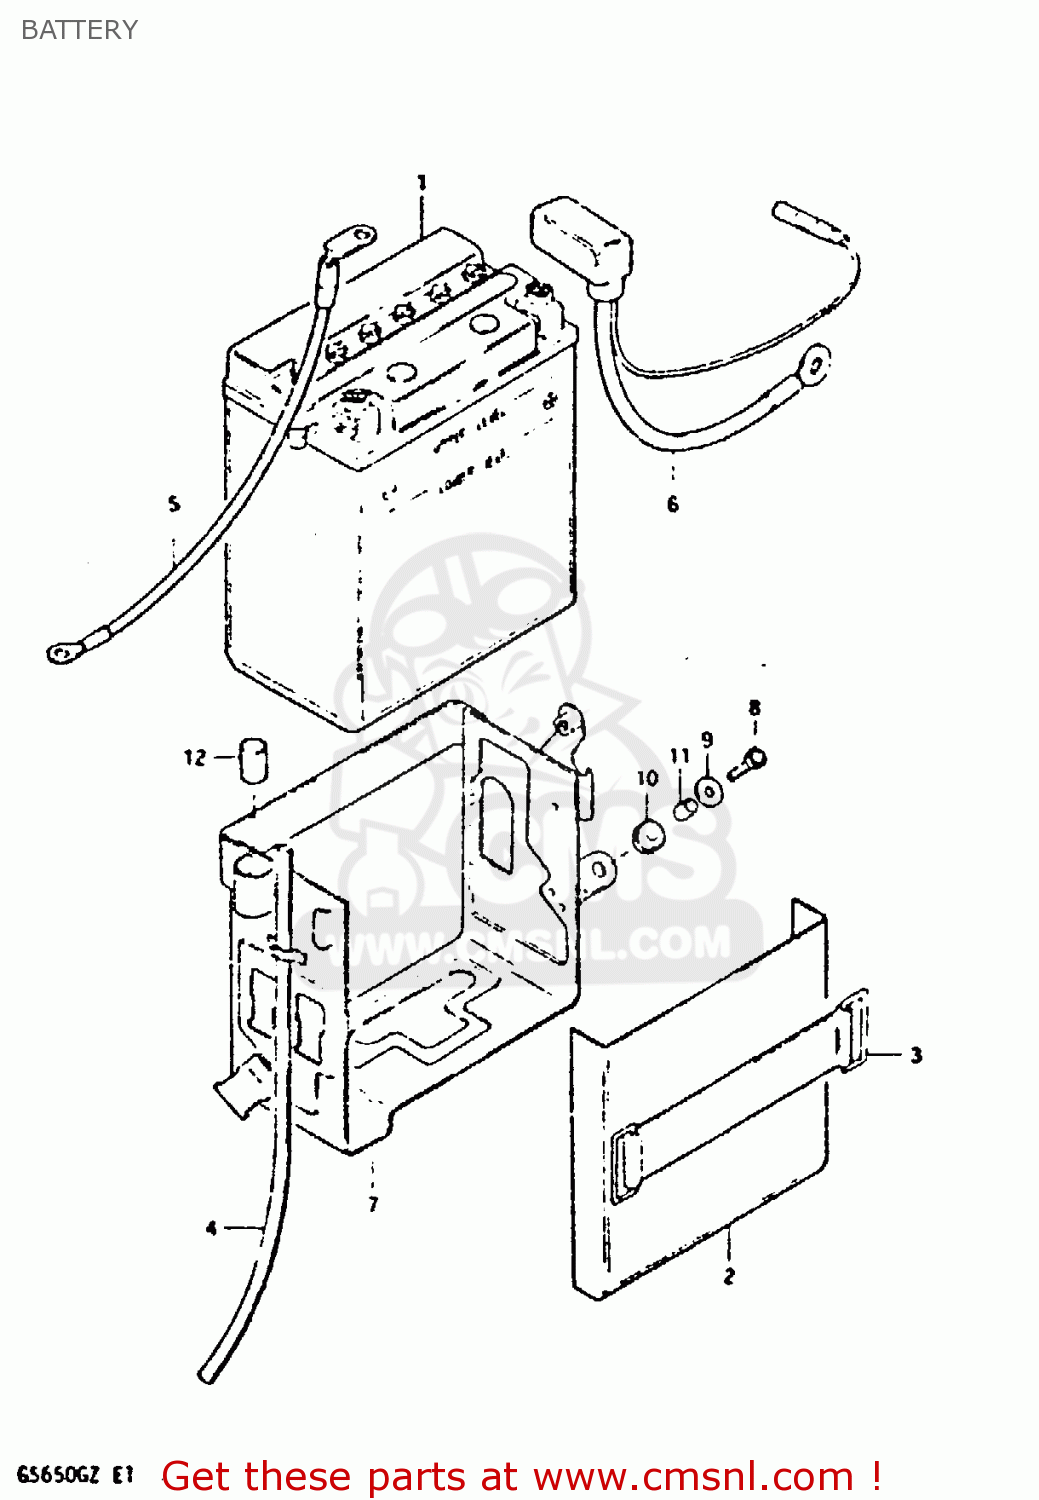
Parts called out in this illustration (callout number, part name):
1	BATTERY ASSY (12V)
2	COVER,BATTERY
3	BAND
4	HOSE,BATTERY EXHAUST
5	CORD,BATTERY MINUS
6	CORD,BATTERY PLUS
7	HOLDER,BATTERY
8	BOLT, UPPER
9	WASHER
10	CUSHION
11	SPACER(6.1X9X7.5)
12	CUSHION
